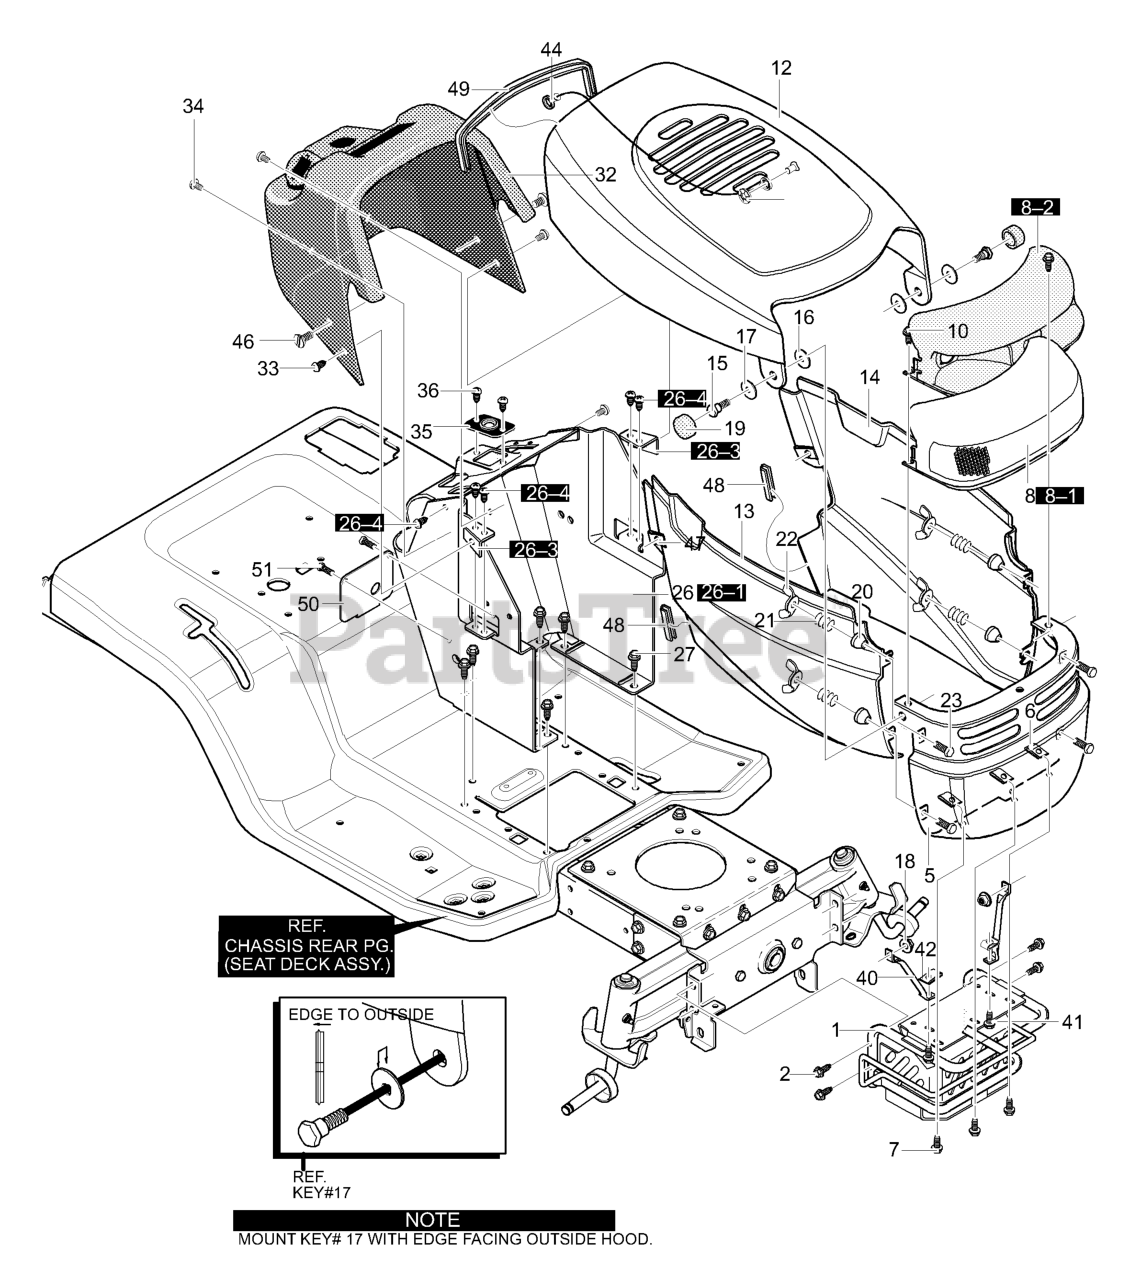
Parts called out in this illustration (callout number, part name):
1	BRACKET, Grille RH
2	SCREW, 5/16-18 x 1.50
6	NUT, "J" Tinnerman
7	SCREW, 1/4-20x.63
8	Lens & Reflector
8-2	Reflector
10	SCREW, 1/4-14x.50
13	PANEL, Side RH
14	PANEL, Side LH
15	BOLT, HHSH 3/8-16
16	WASHER, Plastic
17	PIVOT Base
18	NUT, 3/8-16
19	PIVOT Cap
20	Quick Release
21	SPRING, Comp.
22	NUT, Wing
23	SCREW, 1/4-20x1.25
26	Console Asm.
26-1	Lower Console
26-2	BRACKET, LH
26-3	BRACKET, RH
26-4	SCREW, 10-24x.500
27	SCREW, 5/16-18 x 0.75
33	SCREW, 10-24x.500
34	SCREW, 10-24x.500
35	Steering Bracket
36	SCREW, 1/4-14x.50
40	Strut, Grille
41	SCREW, 1/4-20x.50
42	Speed Nut
44	Lanyard Hood
45	Pushnut
46	SCREW, 1/4-20x.63
47	NUT, "J" Tinnerman
48	Trim 9.50 Inches
49	Trim, 26.80 Inches
50	Access Panel
51	SCREW, 10-24x.500
